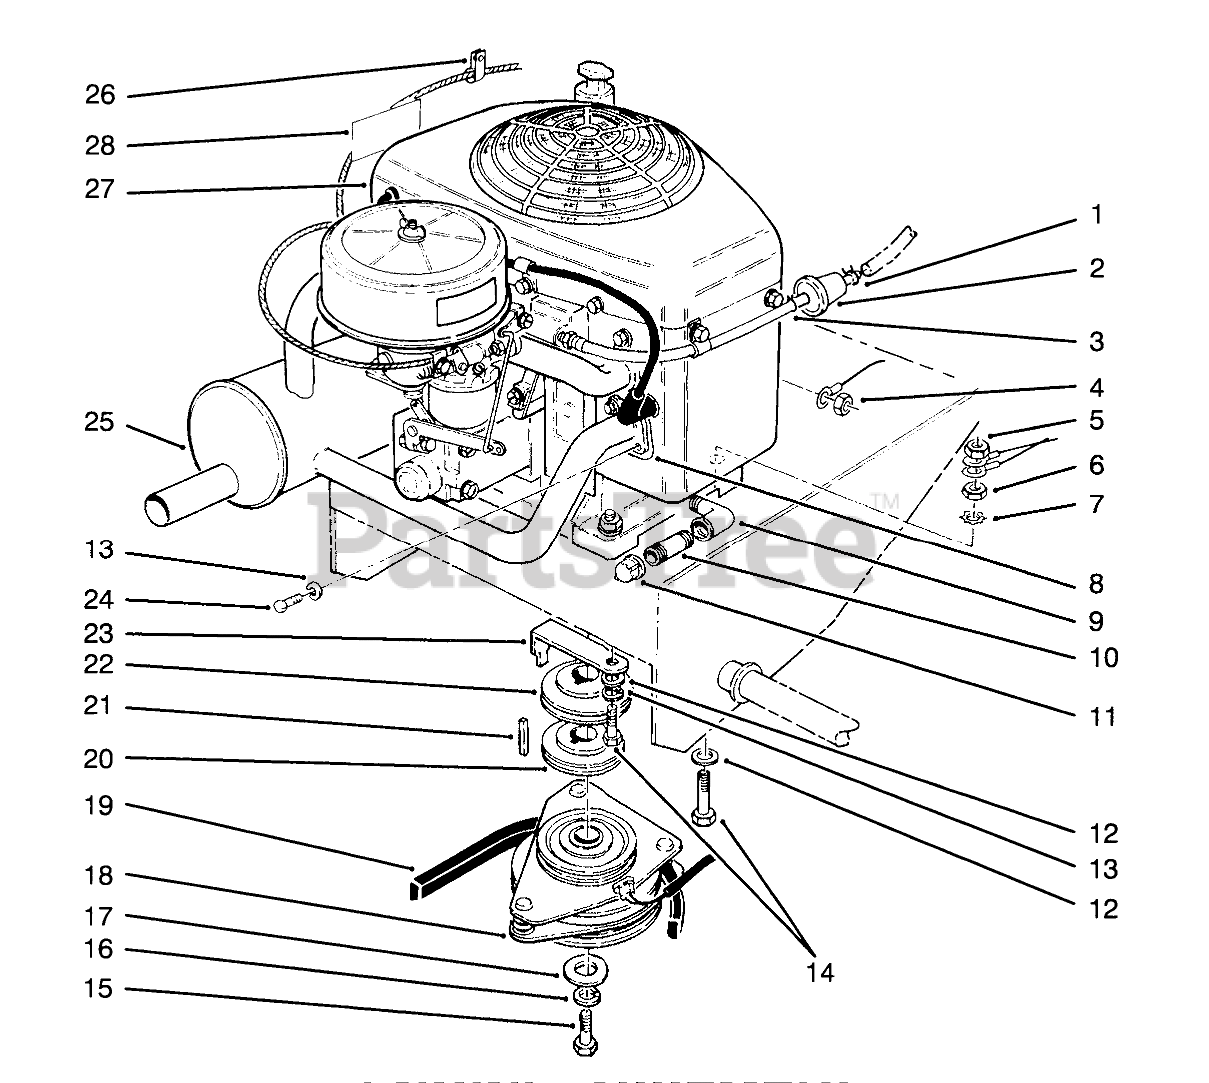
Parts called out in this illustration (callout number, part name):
1	CLAMP-HOSE
2	Fuel-Filter
3	HOSE-FUEL
4	NUT-KEPS
5	NUT-KEPS
6	NUT-LOCK, CONE
7	WASHER-LOCK
8	EXHAUST GASKET F/W ENG.
9	ELBOW-STREET, 90 DEG
10	NIPPLE
11	CAP-PIPE
12	WASHER-PLAIN
13	WASHER-LOCK
14	SCREW-HH
15	SCREW-HH
16	WASHER-LOCK
17	WASHER-CLUTCH
18	CLUTCH/BRAKE
19	V-BELT, DRIVE
20	SHEAVE-LOWER HALF
21	KEY-SQUARE
22	SHEAVE-UPPER HALF
23	Retainer-Clutch
24	SCREW-HSH
25	MUFFLER
26	CLAMP-R
28	Decal-Hot
